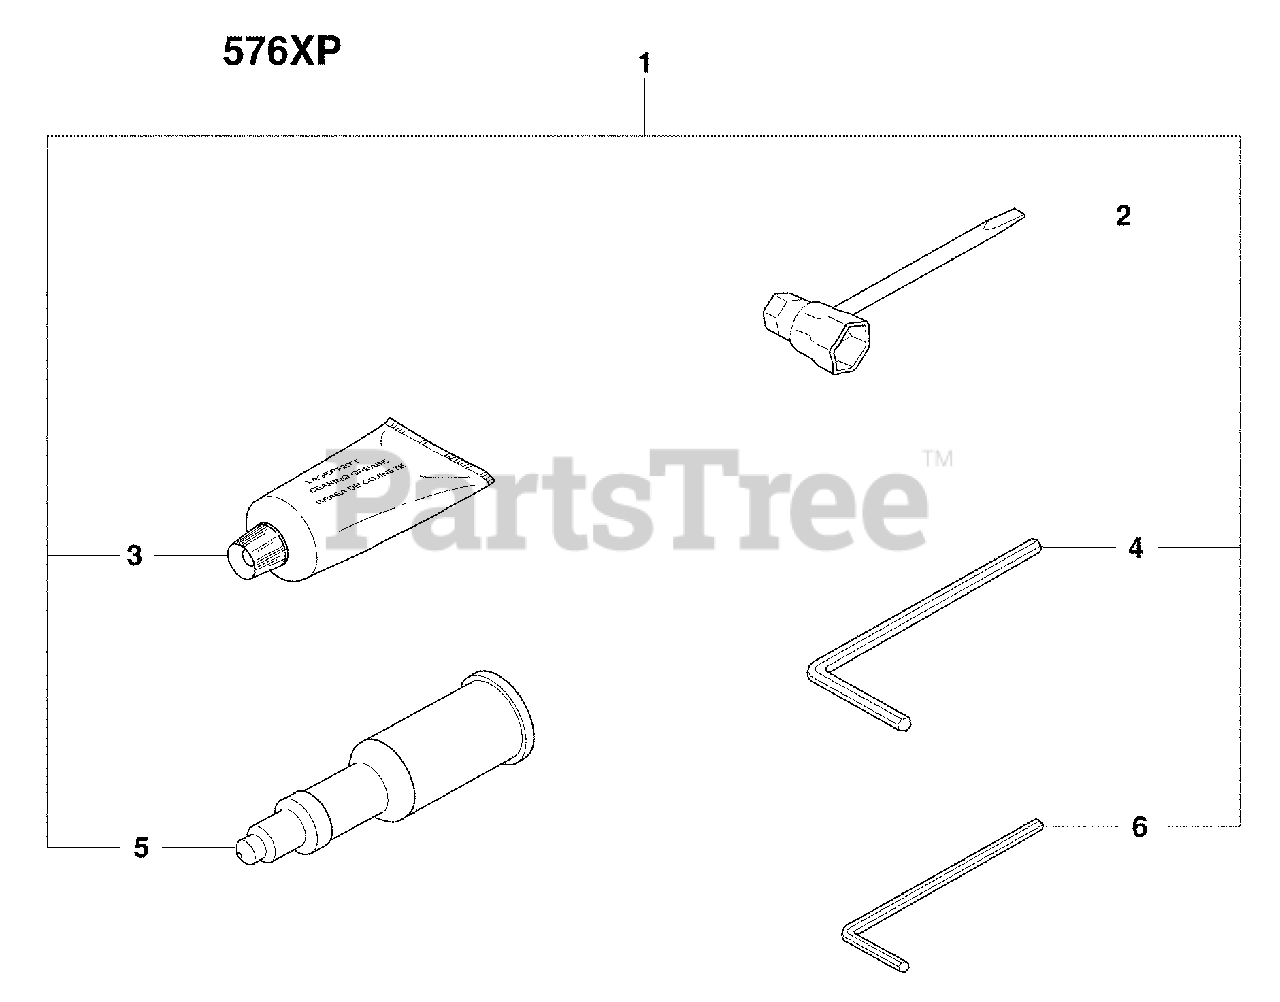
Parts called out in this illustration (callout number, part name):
1	Combi Tool
2	Combi Tool
3	Bearing Grease Tube
5	Grease Gun
